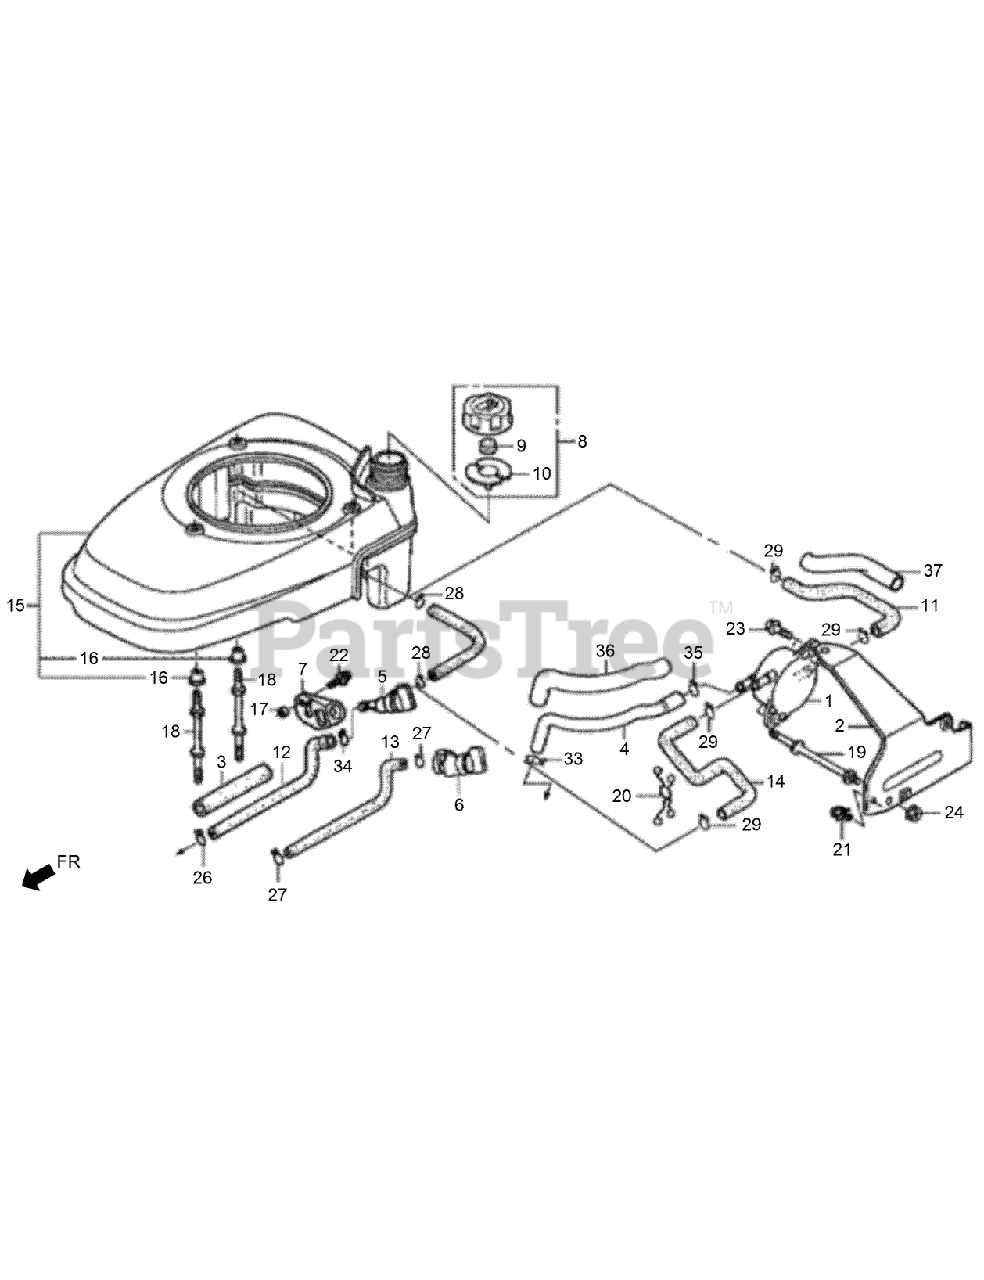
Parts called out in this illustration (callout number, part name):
1	PUMP ASM-FUEL
2	STAY-FUEL PUMP
3	RUBBER-SUPPORTER
4	TUBE-DIAPHRAGM
6	COCK ASM-FUEL
7	BRACKET-FUEL COCK
8	CAP ASM-FUEL TANK
9	SPONGE-FUEL CAP BREATHER
10	PACKING-FUEL CAP
11	TUBE-FUEL TANK
12	TUBE-FUEL
13	TUBE-FUEL
14	TUBE B-FUEL
15	FAN COVER ASM (NH1)
16	COLLAR-FAN COVER
17	COLLAR-FR WINKER
18	BOLT-STUD
19	BOLT-STUD
20	CLIP-PURSE LOCK
21	CLIP-WIRE HARNESS
22	SCREW-WASHER-5X10
23	SCREW-WASHER-5X14
24	NUT-FLANGE-6MM
26	CLIP-TUBE
27	CLIP-TUBE
28	CLIP-TUBE
29	CLIP-TUBE
33	CLIP-TUBE
34	CLIP-TUBE
35	CLIP-TUBE
36	TUBE-VINYL-9X11X210
37	TUBE-VINYL-11X13X100
